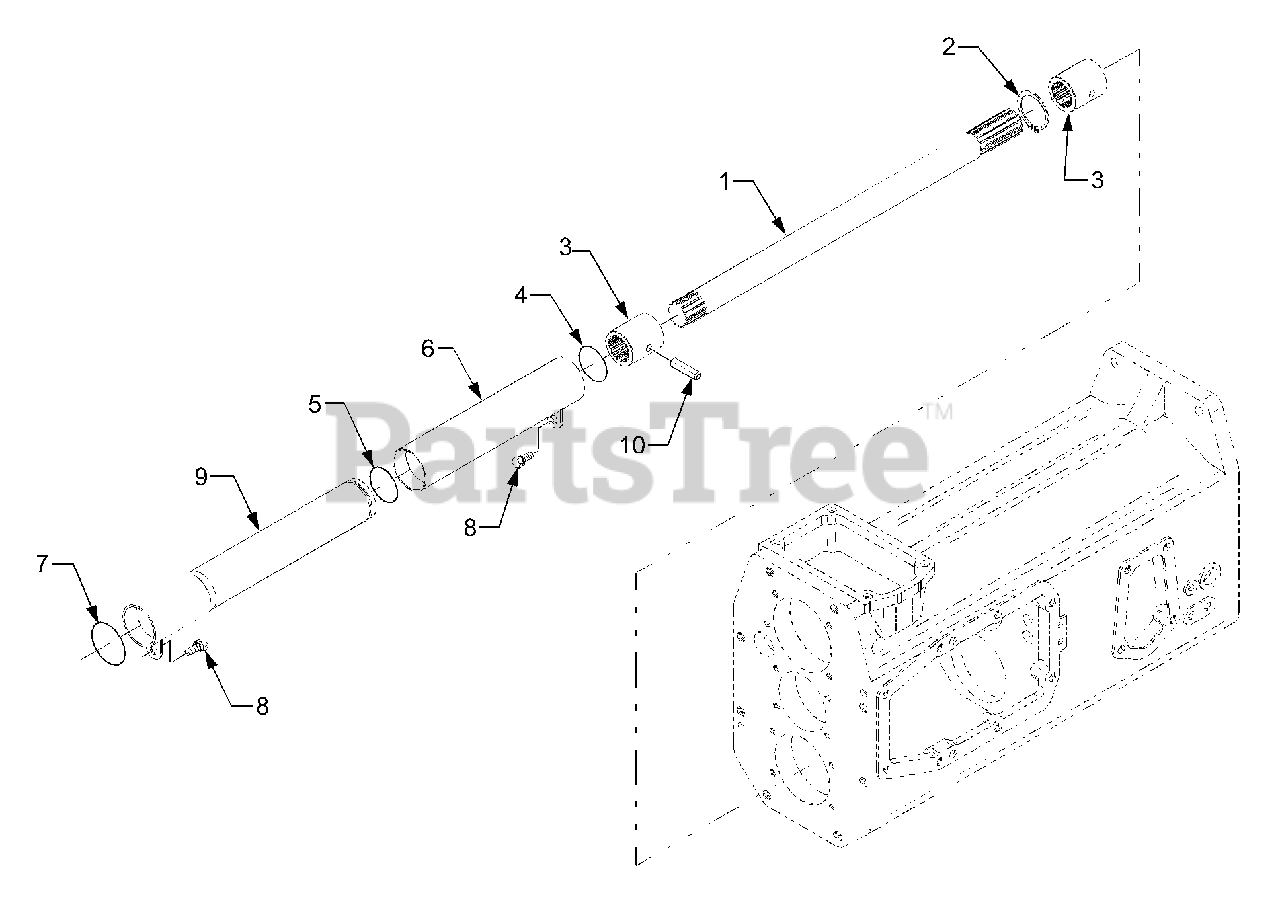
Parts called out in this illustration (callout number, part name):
1	Shaft 2, Propeller
6	Cover 1, Propeller Shaft
9	Cover 2, Propeller Shaft
